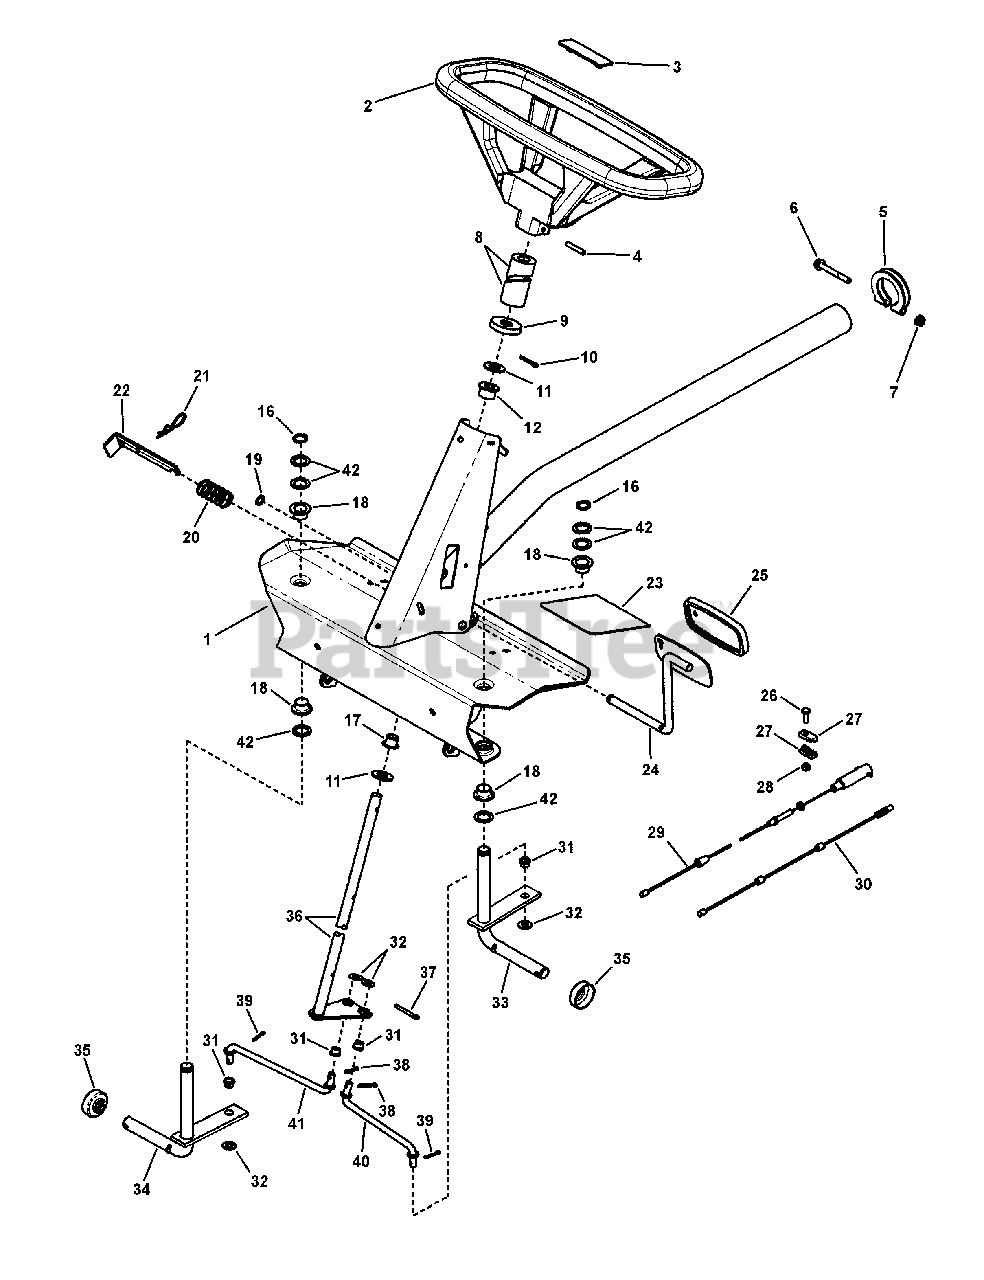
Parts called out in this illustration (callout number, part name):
1	WELDMENT, Front Axle, Narrow, Red
2	ASSEMBLY, Steering Wheel (for 5/8 shaft)
3	LOGO, Steering Wheel, Snapper
4	ROLL PIN, 1/4 x 1-1/2"
5	CLAMP, Tube
6	SCREW, 5/16-24 x 2-1/2" Hex Head Cap, GR 5
7	NUT, 5/16-24 Hex Flange Lock, BZ
8	FOAM COVER, Steering Shaft
9	COVER, Steering Shaft
10	PIN, 3/16 x 1" Cotter
11	WASHER, .66 x 1.31 x .09 Flat
12	BUSHING, Nylon
16	RETAINING RING, 3/4" ID, ZC/CL
17	BUSHING, Nylon
18	BEARING, Nylon
19	RING, 1/2 External Retaining
20	SPRING, Parking Brake Latch
21	HAIR PIN, 2-1/4"
22	LATCH, Parking Brake
23	FOOT PAD, Short (5.5 x 4.7)
24	WELDMENT, Clutch Pedal
25	PAD, Clutch/Brake Pedal
26	SCREW, 1/4-20 x 3/4 Hex Head Cap, GR 5, Zinc/Clear
27	CONNECTOR, Cable (Single Part)
28	NUT, 1/4-20, Center Lock, GR 5, Zinc/Clear
29	CABLE, Brake, Snap-In
30	CABLE, Clutch/Brake, 54.32" long
31	BUSHING, Tie Rod
32	WASHER, .406
33	WELDMENT, King Pin, Left Hand, Black
34	WELDMENT, King Pin, Right Hand, Black
35	CAP, Dust
36	WELDMENT, Steering Shaft, Black
37	PIN, 3/16 x 1-1/2 Cotter
38	PIN, 5/32 x 1 Cotter
39	PIN, 1/8 X 0.75, Cotter, Zinc/Clear
40	TIE ROD, Left Hand (7.41" long)
41	TIE ROD, Right Hand (7.41" long)
42	WASHER, .77 x 1.13 x .06, Flat
